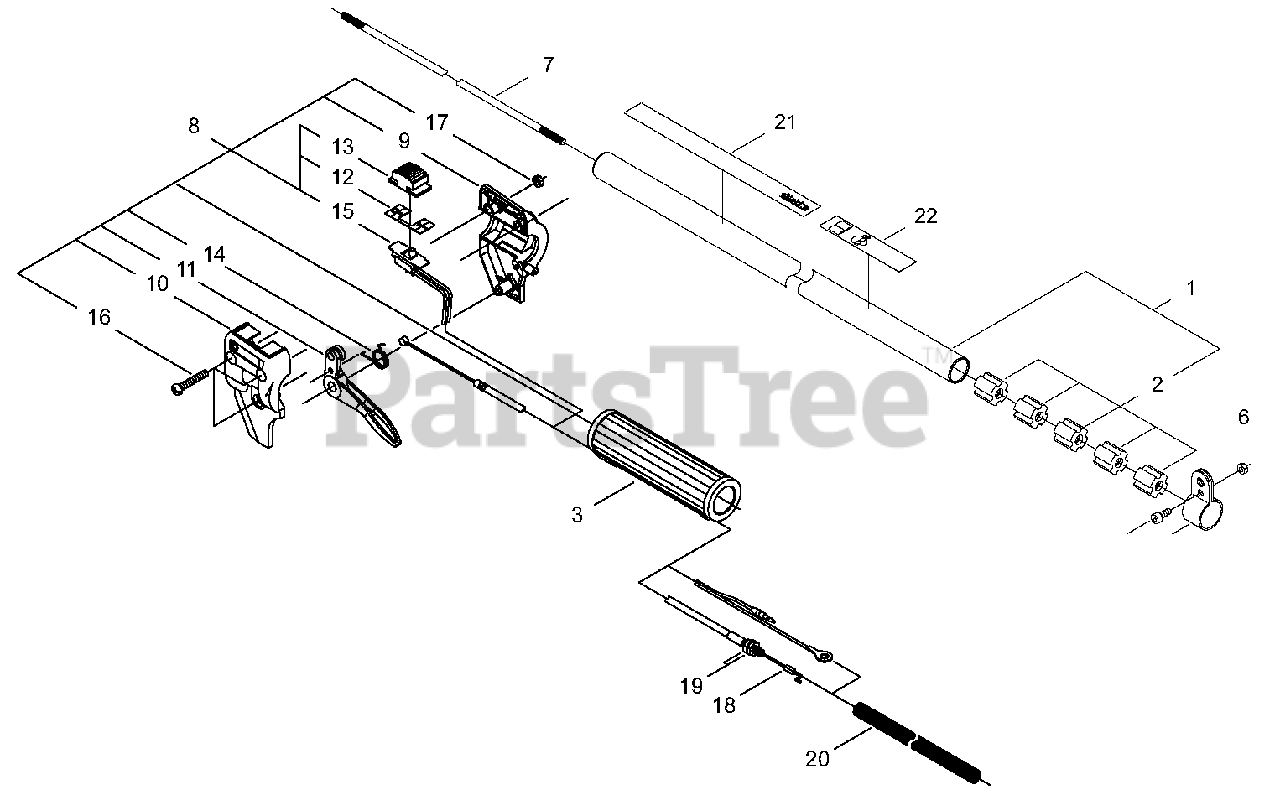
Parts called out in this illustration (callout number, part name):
1	MAIN PIPE ASSY
2	BUSHING
3	GRIP, REAR
4	HANGER
5	BOLT 5×12
6	NUT M5
7	MAINSHAFT
8	THROTTLE CONTROL KIT
9	CONTROL HANDLE - RIGHT
10	CONTROL HANDLE - LEFT
11	TRIGGER, THROTTLE
12	PLATE, SWITCH
13	KNOB, SWITCH
14	SPRING, RETURN
15	SWITCH
16	SCREW M5×30
17	NUT M5
18	CABLE, THROTTLE
19	NUT M6
20	TUBE, PLASTIC PROTECTIVE
21	LABEL, SHINDAIWA PROFESSIONAL
22	LABEL, CAUTION
